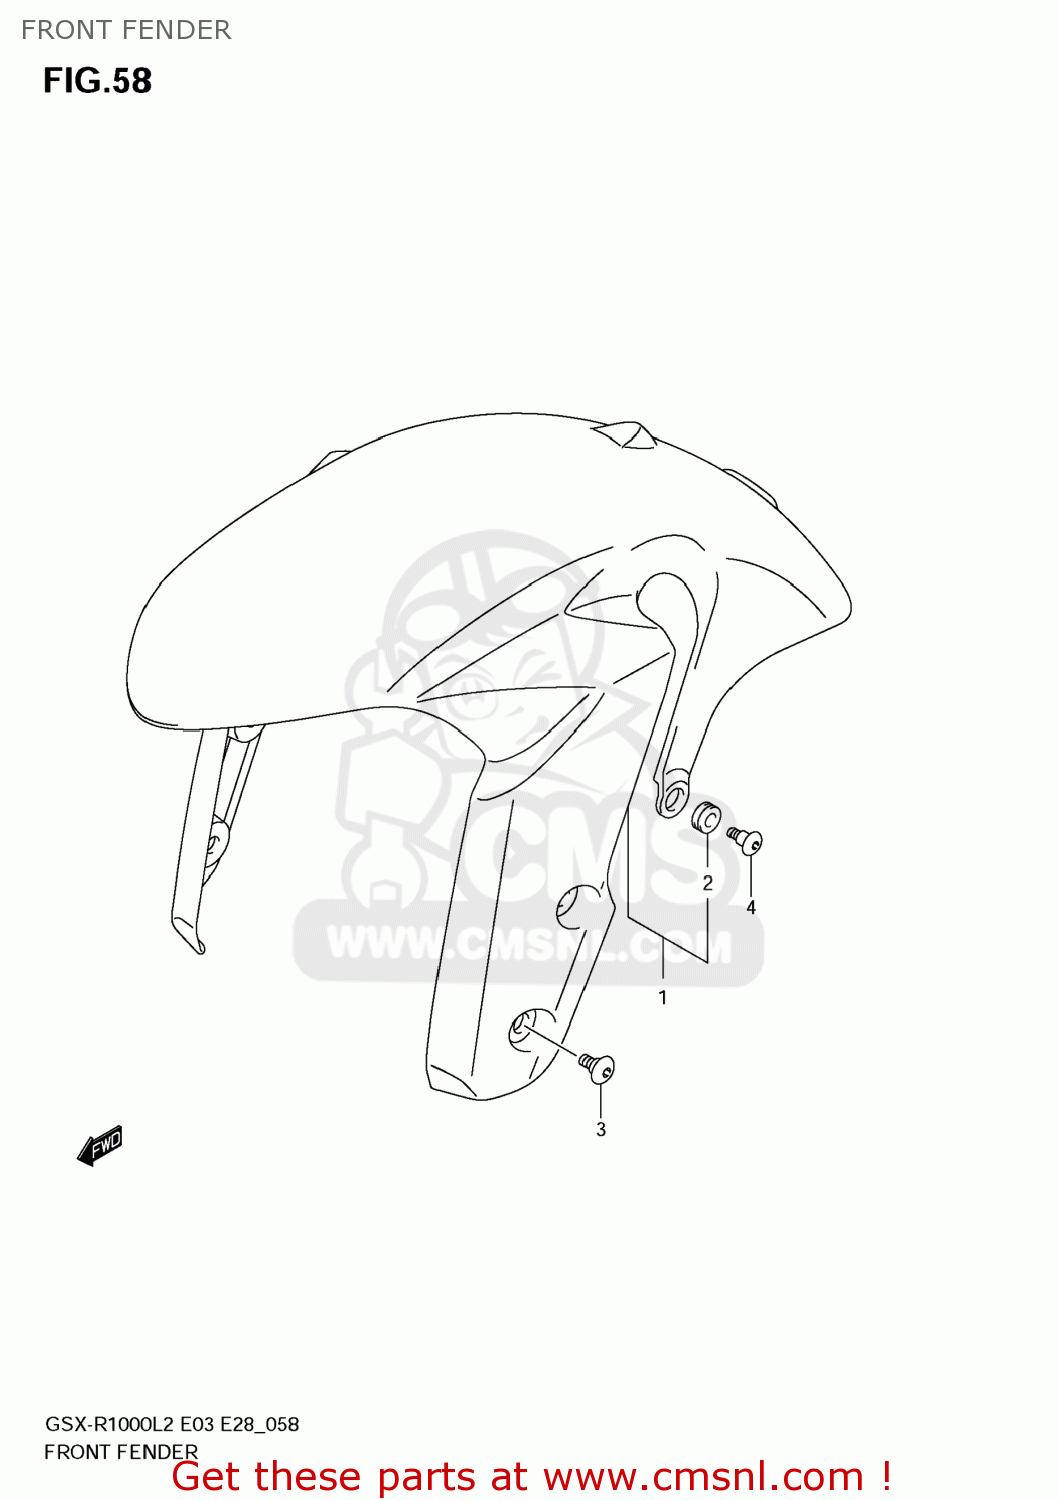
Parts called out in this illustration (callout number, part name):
1	FENDER ASSY,FR(BLUE)
2	CUSHION
3	SCREW(6X16)
4	SCREW(6X16)
